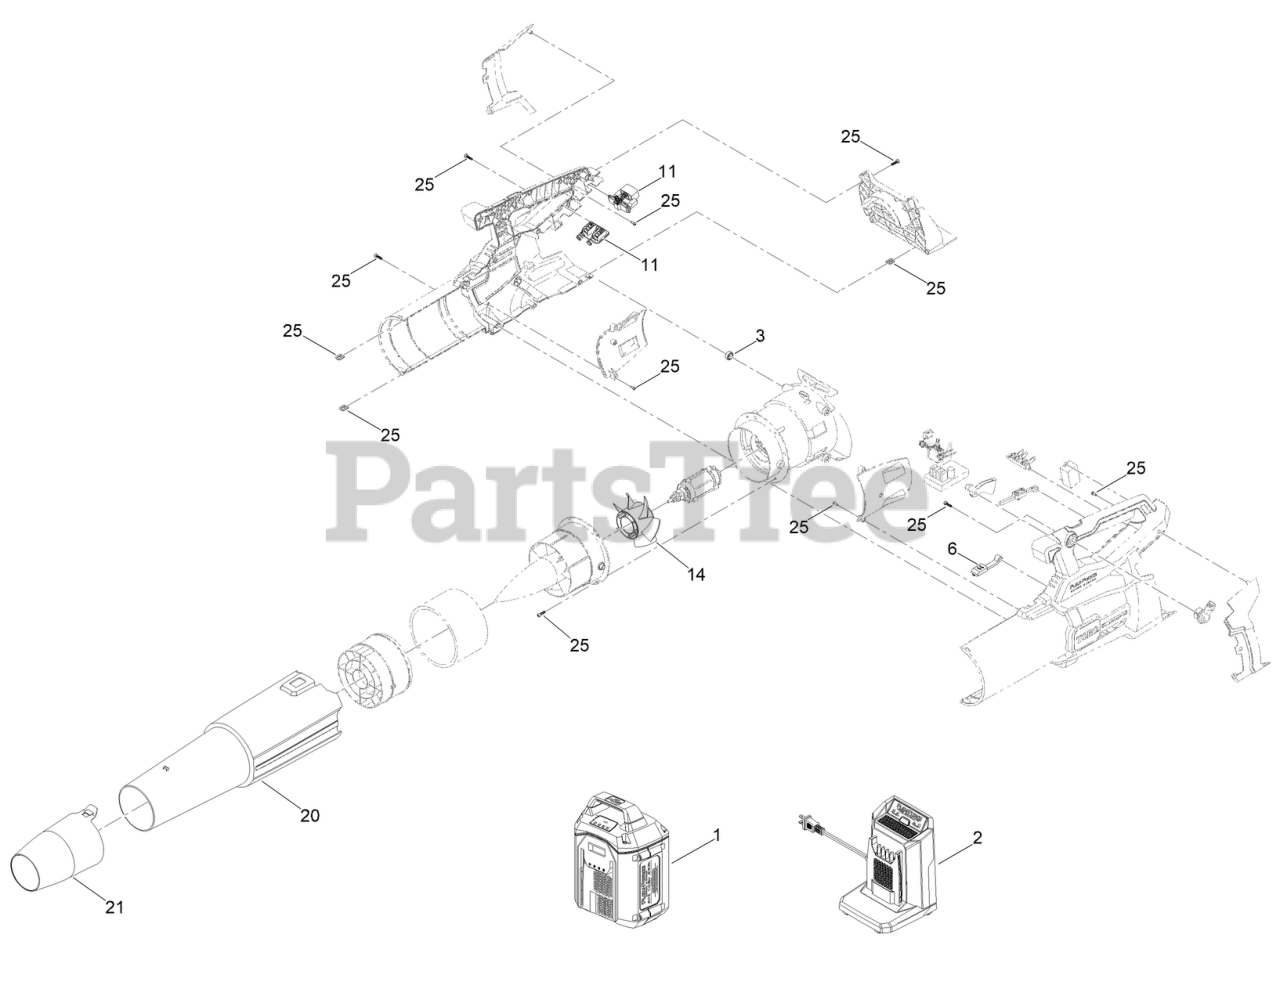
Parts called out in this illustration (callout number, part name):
1	BATTERY-LI-ION, 60V 2.5AH, 135WH
2	CHARGER-BATTERY 60V 2.0AMP
3	60V AXIAL BLOWER ISOLATOR KIT
6	BLOWTUBE RELEASE SERVICE KIT
11	60V AXIAL BLOWER BATTERY LATCH
14	60V BLOWER FAN SERVICE ASM
20	60V AXIAL BLOWER BLOW TUBE
21	60V AXIAL BLOWER REDUCER NOZZLE
25	60V AXIAL BLOWER HARDWARE KIT
